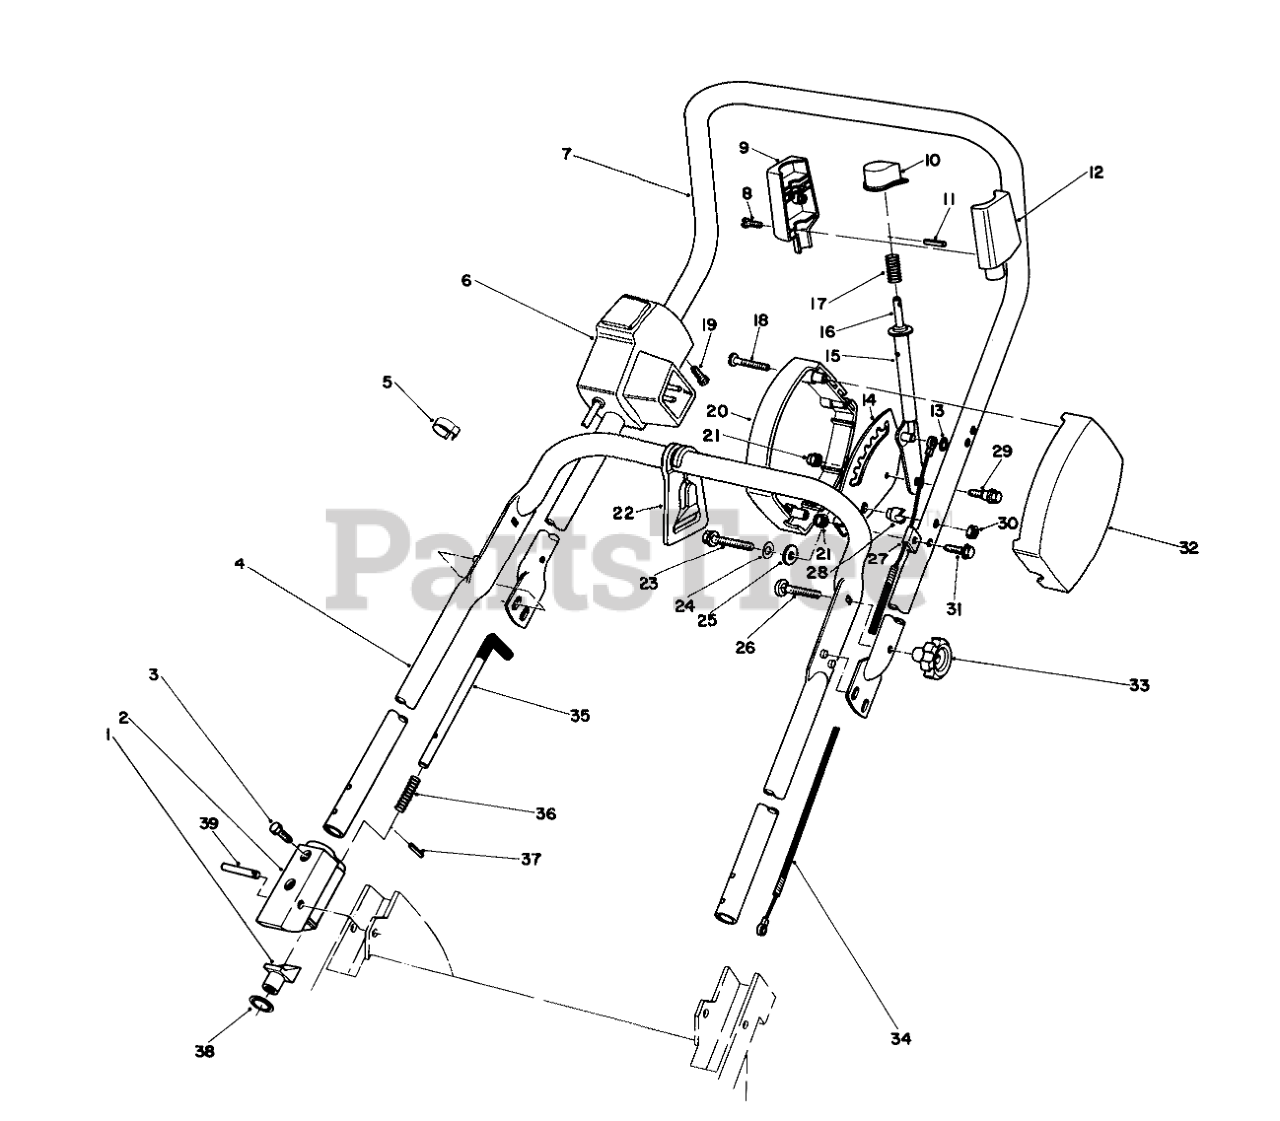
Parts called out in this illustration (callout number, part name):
1	Bushing-Insulated
2	Block-Handle Mounting
3	SCREW-SHWH, THREAD FORMING
4	Lower Handle
6	Switch On-Off
7	Upper Handle
8	Screw-Pan Head
9	Grip-Right Hand
10	Button-Height of Cut
11	PIN-SPRING
12	Grip-Left Hand
13	PUSH NUT
14	Bracket-Detent
15	Handle-Height fo Cut
16	Rod-Detent
17	COMPRESSION SPRING O
18	8 X1.25 SELF TAP SCRW
19	SCREW-PPH
20	Cover-Control R.H.
21	M6 X 1 LOCKNUT
22	Retainer-Cord
23	Capscrew
24	WASHER-PLAIN
25	Washer-Insulator
26	SCREW-CARR
27	Clamp-Cable
28	Isolator-Control
29	Shoulder Screw
30	NUT-LOCK
31	Screw-Cap Hex. Hd.
32	Cover-Control L.H.
34	UPPER CABLE
35	Rod-Latch
36	COMPRESSION SPRING
37	PIN-ROLL, SLOTTED
38	Speed Nut-Push On
39	Pin-Handle Mounting
